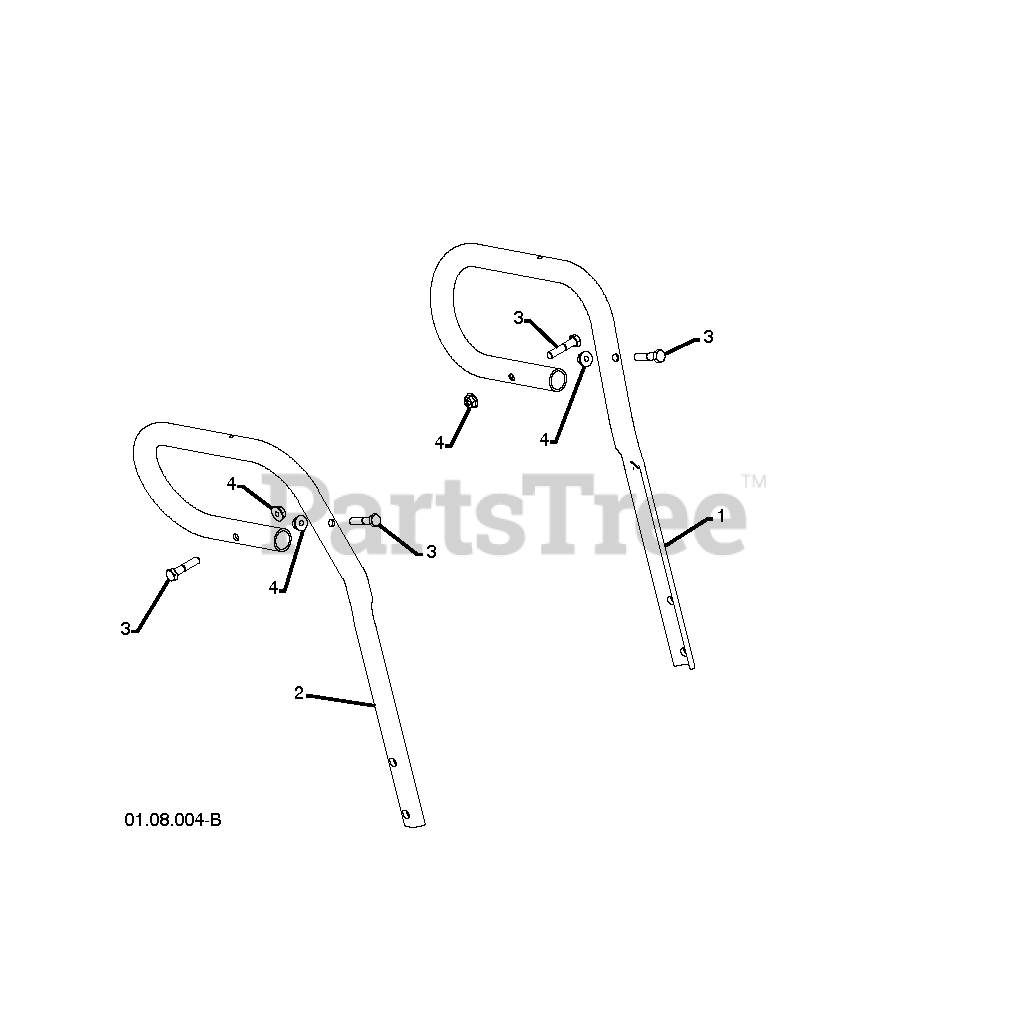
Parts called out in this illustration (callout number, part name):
1	TUBE.HANDLE.LOOP.LH.BLACK
2	TUBE.HANDLE.LOOP.RH.BLACK
3	HEX BOLT
4	NUT, LOCK 5/16-18
